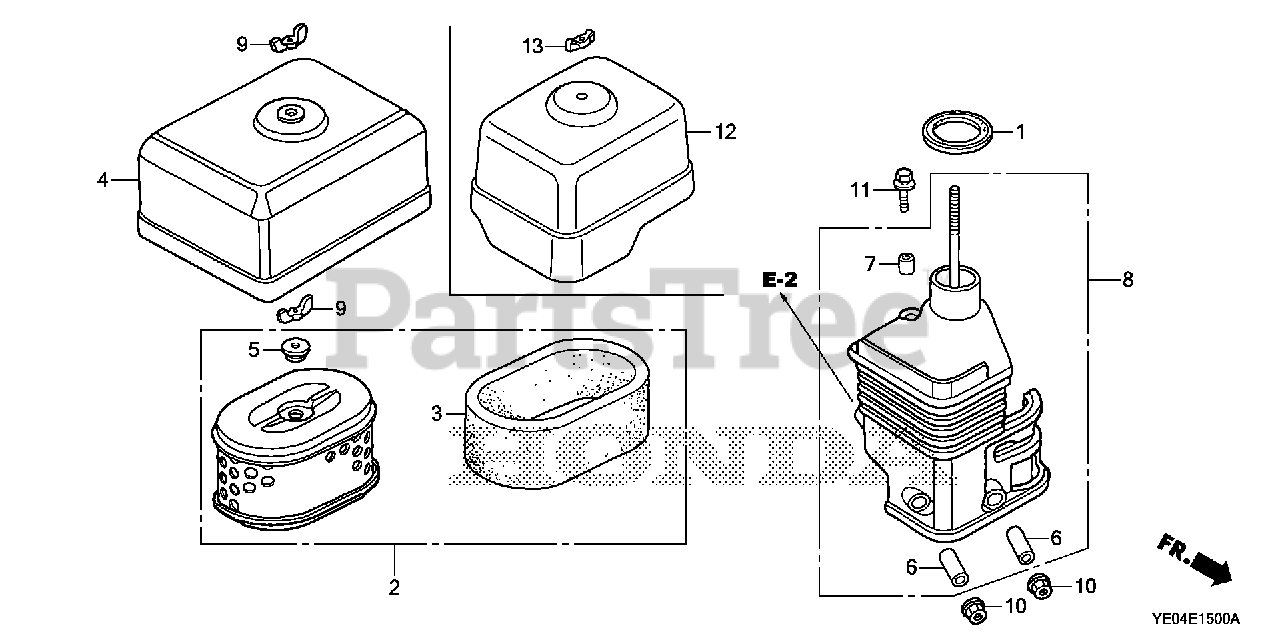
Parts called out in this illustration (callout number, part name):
1	GASKET, ELBOW
2	ELEMENT, AIR CLEANER (DUAL) Use up to Engine SN 2115700.
2	ELEMENT, AIR CLEANER (DUAL)
3	FILTER (OUTER)
5	GROMMET, AIR CLEANER
6	COLLAR, AIR CLEANER Use from Engine SN 1786085.
7	COLLAR B, AIR CLEANER
8	ELBOW, AIR CLEANER
9	WINGNUT, TOOL BOX SETTING
10	NUT, FLANGE (6MM)
11	BOLT, FLANGE (6X20)
12	COVER, AIR CLEANER
13	NUT, AIR CLEANER
